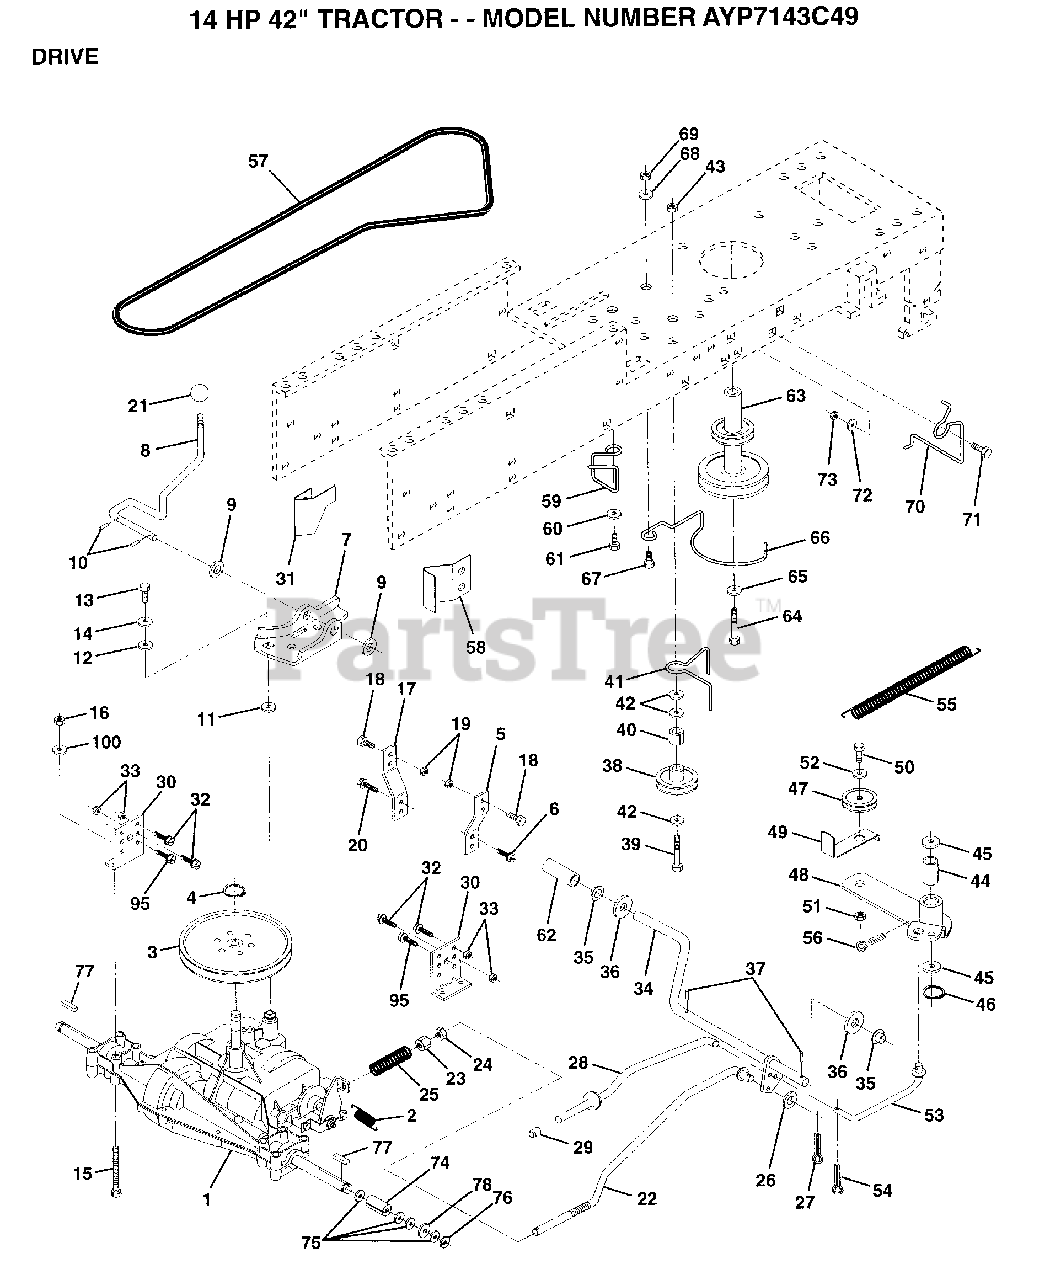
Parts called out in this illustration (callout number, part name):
3	PULLEY TRANS
5	STRAP TORQUE
6	SCREW
8	SHIFT ROD
9	WASHER
10	PIN COTTER 1/8
11	WASH-SHFT PLT LT
12	WASHER LT
14	LOCKWASHER
15	BOLT HEX
17	STRAP TORQUE
18	BOLT
19	NUT
20	SCREW
21	KNOB T (1/2-HOLE)
22	BRAKE ROD
23	NUT
24	NUT
25	SPRING ROD LT
26	WASHER
27	COTTER PIN
28	ROD PARK BRAKE
29	PLUNGER CAP T
30	TRANSAXLE MTG BKT
31	"KEEPER,BELT LH T"
32	BOLT
33	NUT
35	NYLON BEARING
36	WASHER LT
38	PULLEY.IDLER.FLAT
39	BOLT
40	SPACER T
41	BELT KEEPER LT
42	WASHER
43	NUT
44	"LY, BEARING"
45	WASHER LT
46	KLIP RING
48	ARM IDLER
49	RETAIN BELT
52	WASHER
53	"LINK, CLUTCH T"
54	COTTER PIN
55	"SPRING, RETURN LT"
56	COTTER PIN
58	"KEEPER,BELT RH T"
59	KEEPER BELT CNTSP
60	WASHER
61	SCREW
62	PEDAL COVER T
63	PULLEY.ENGINE
64	BOLT
65	LOCKWASHER
66	KEEPER.BELT.ENG.L
67	BOLT
68	WASHER
70	KEEPER BELT ENG
71	BOLT
72	WASHER
74	SPACER LT
75	WASHER
76	E-RING LT
77	SQUARE KEY
78	WASHER
95	SCREW
100	WASHER M
